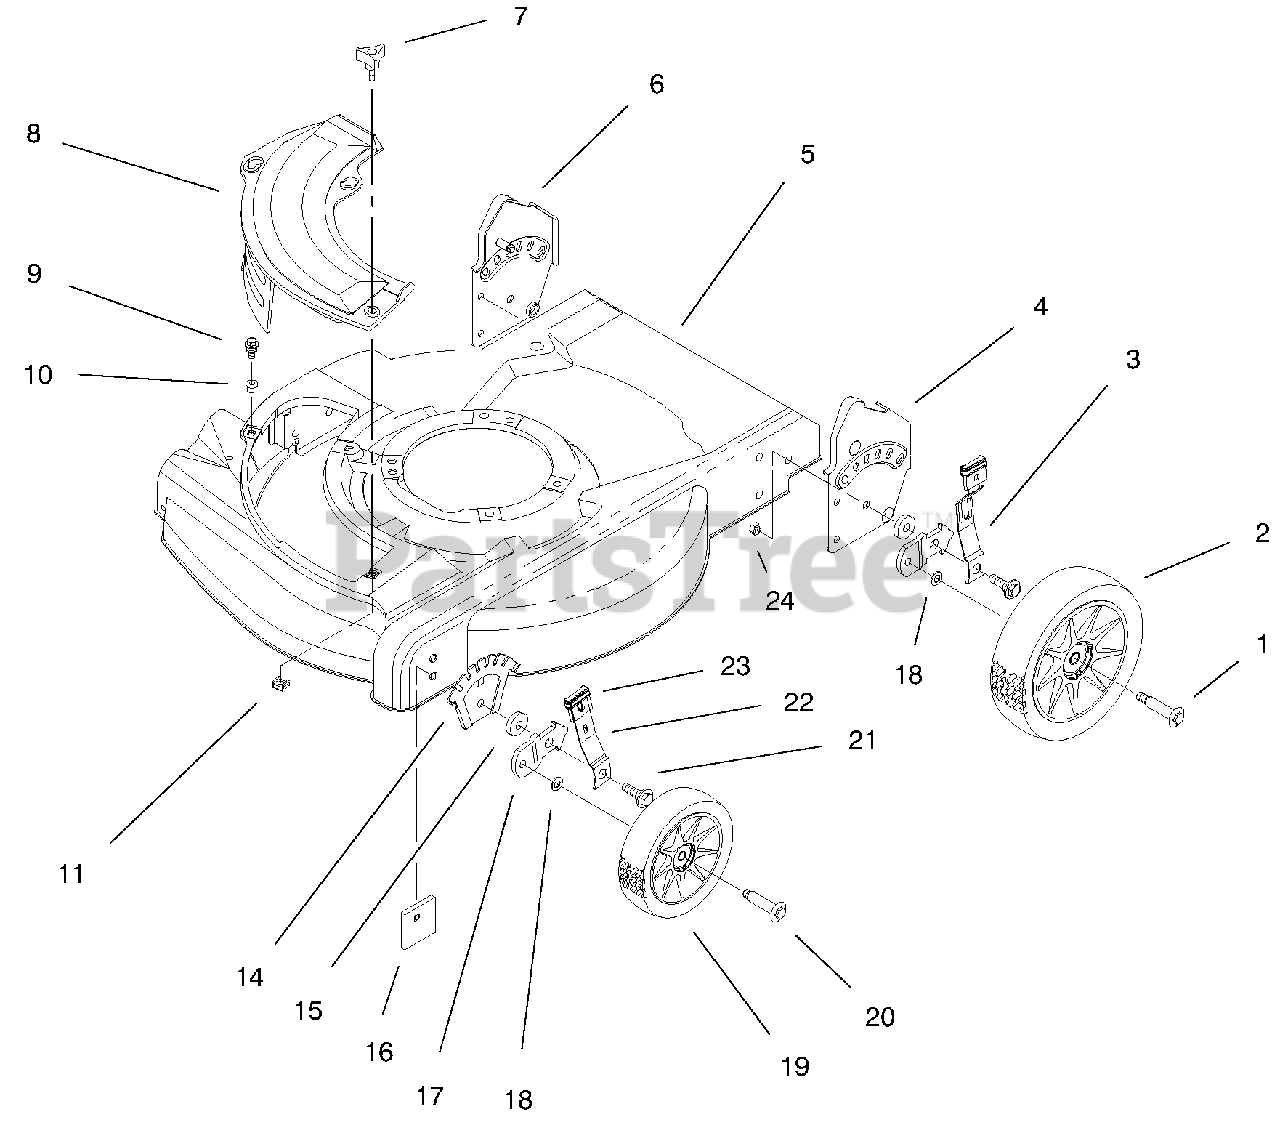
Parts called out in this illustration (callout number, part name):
1	Bolt-Shoulder
2	Wheel & Tire Ass'y 8"
3	Spring Arm Assembly
4	Bracket-Handle L.H.
5	Housing Assembly
6	Bracket-Handle R.H.
7	Knob-Cover Plate
8	Plate-Mulch 21"
9	Screw-Sems Thr'd Form
10	Grommet-Plastic
11	Nut-Cage
14	Plate-Height Adjust
16	Plate-Baffle
17	Bracket-Wheel Height Adj.
19	Wheel-Tire Assembly 6"
20	Bolt-Shoulder
21	Bolt-Shoulder
22	Spring Arm Ass'y-Front
23	Knob-Height Adjust.
24	Nut-Lock
